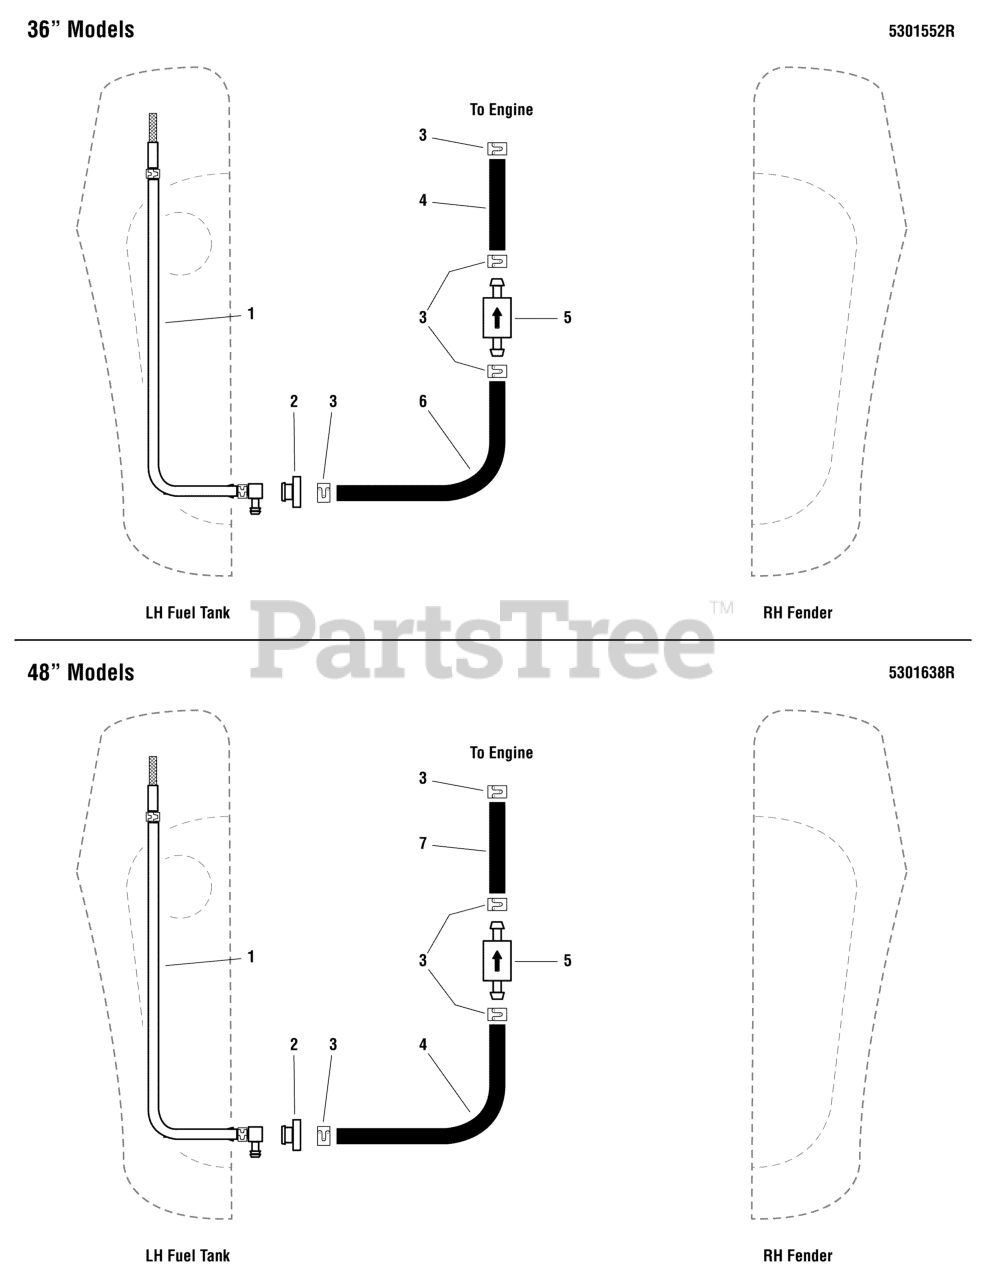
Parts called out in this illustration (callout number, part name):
1	PICKUP TUBE ASM, FUEL TANK, 18.38" (SV)
2	BUSHING-FUEL TANK RED RUBBER
3	CLAMP, HOSE, EXTERNAL, 1/2 - RED
4	HOSE, 1/4 FUEL LINE, 10"
5	FUEL FILTER (SV)
6	HOSE, 1/4 FUEL LINE, 28"
7	HOSE, 1/4 FUEL LINE, 31"
